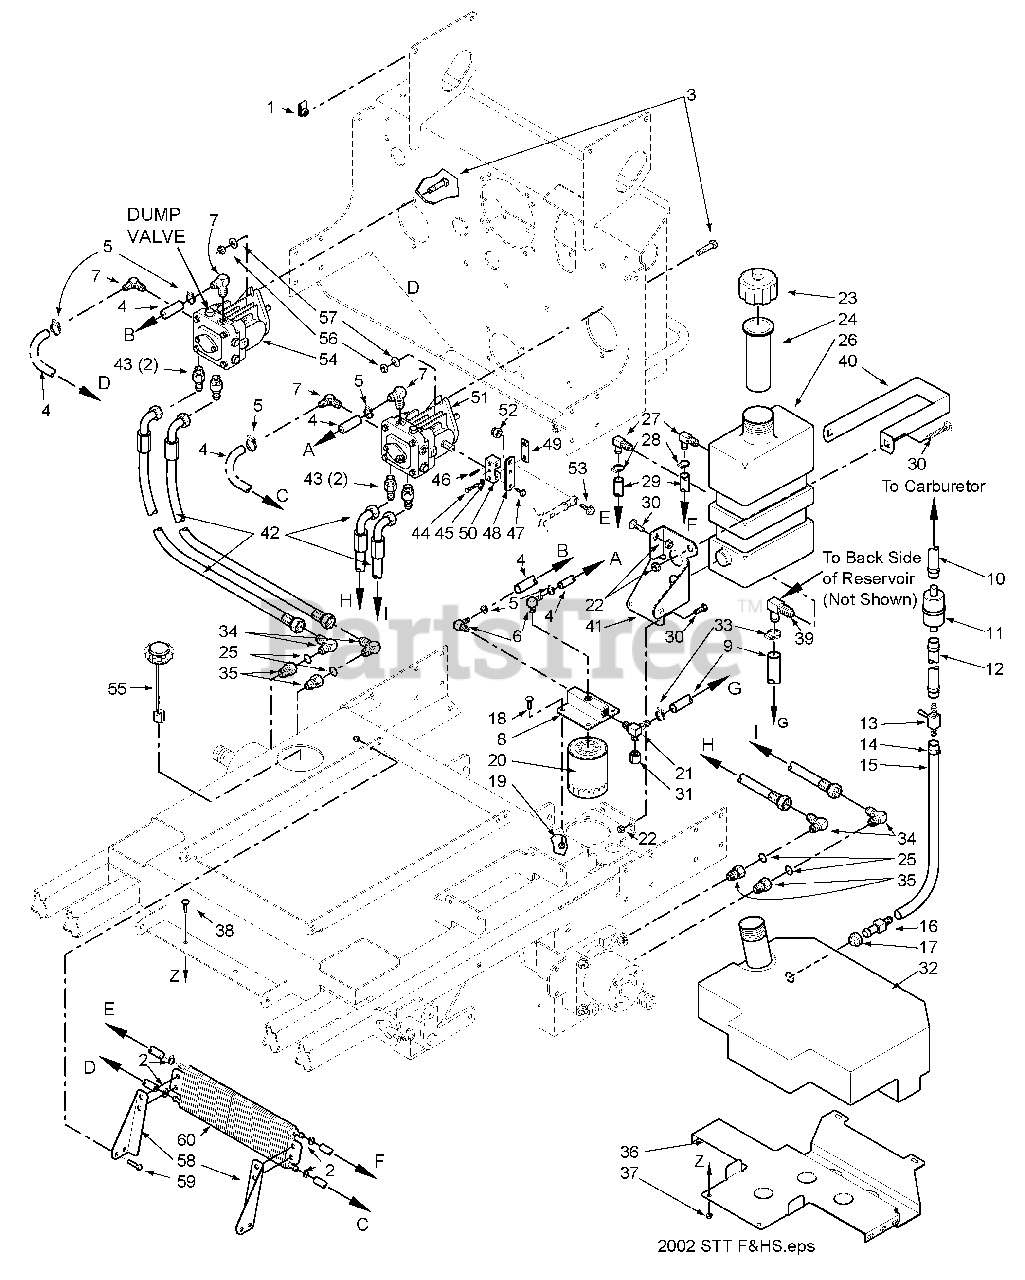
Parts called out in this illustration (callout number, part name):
1	U-Nut 1/4-20
2	Hose Clamp, 0.69 dia.
3	Bolt, Hex Head 1/4-20 x 2.0"
4	Hose, 3/8" ID Pushlock
5	Clamp, Hose 1/2"
6	Elbow, 90 Degree - 1/4 NPT x 3/8 Hose
7	Elbow, 90 Degree - 9/16 O-ring x 3/8 Hose
8	Oil Filter Base
9	Hose Assembly, 1/2" ID (Tank to Filter Base)
10	Fuel Hose to Carb.
11	Fuel Filter
12	Fuel Hose, 1/4" ID
13	Valve, Shutoff Kawasaki
14	Clamp, Fuel Hose
15	Fuel Hose, 1/4" ID
16	Hose Fitting
17	Bushing
18	Bolt, Hex Head 5/16-18 x1.0" Zinc
19	Nut, Serrated Flange 5/16-18
20	Oil Filter
21	Tee, 3/4 O-ring x JIC x 1/2" Hose
22	Nut, Hex Elastic Stop 1/4-20
23	Cap, Hydraulic Tank
24	Insert, Filler Neck
25	O-Ring
26	Oil Reservoir Assembly
27	Elbow, 90 Degree .38 Hose
28	Hose Clamp, 0.69 dia.
29	Hose, 3/8" ID, Pushlock
30	Screw, Phillips Head, 1/4-20
32	Fuel Tank Assembly
33	Clamp, Hose
34	Elbow, 90 Degree, 7/8-14 THD
35	Bushing, 7/8-14 JIC x 3/4-16 O-Ring
36	Support Bracket, Fuel Tank
37	Nut, 5/16-18 Serrated Flange
38	Bolt, Carraige 1/4-20 x 3/4"
39	Elbow, 90 Degree
40	Bushing, .78 Dia. Viton
41	Strap, Hydraulic Tank
42	Support Bracket, Hydraulic Tank
43	Hose Assembly, Pump
44	Union, 3/4-16 JIC x 3/4-16 O-ring
45	Bolt, Hex Head, 1/4-20 x 1-14"
46	Lockwasher, 1/4" Spring
47	Roll Pin, Spring 3/16 x 3/4"
48	Bolt, Hex Serrated Flange, 1/4-20 x 3/4"
49	Clamp, .69 Dia.
50	Clamp Plate, Pump Control
51	Block, Pump Control
52	Pump, Left Hand, BDP-16A (31BV)
53	Nut, Hex, Elastic Stop 3/8-16
54	Bolt, Hex Head, 3/8-16 x 1-1/4
55	Pump, Right Hand, BDP-16A (31BV)
56	Cap, Fuel Tank W/Guage
57	Nut, Hex Elastic Stop 3/8-16
58	Flatwasher, 3/8" (.391 x .938 x .105) Grade 8
59	Mounting Bracket - RH, Oil Cooler
60	Bolt, Hex Head 5/16-18 x 3/4"
